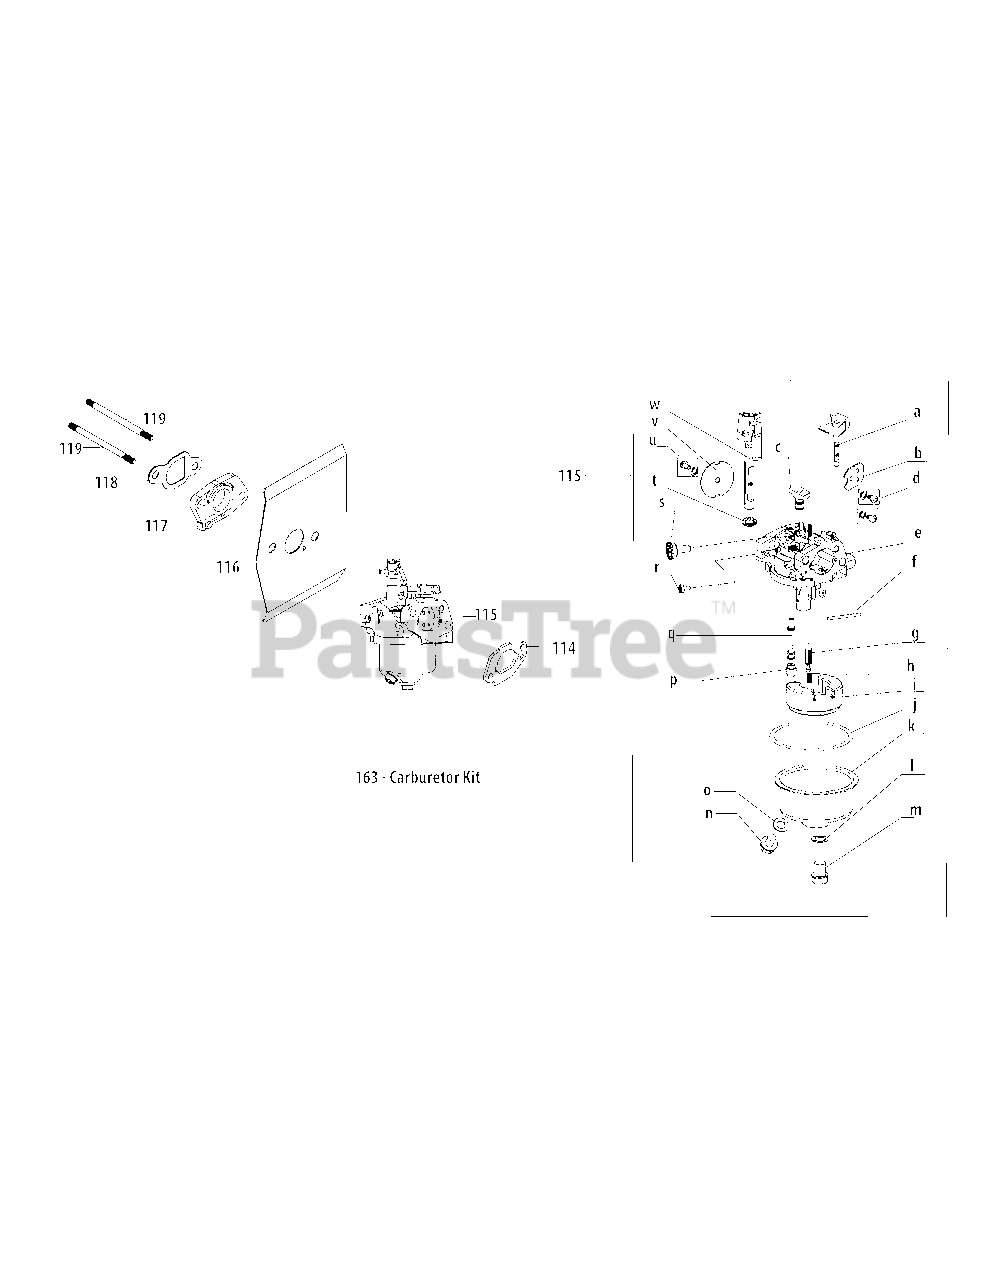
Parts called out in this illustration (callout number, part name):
114	Air Filter Base Gasket
115	Carburetor Assembly
116	Carburetor Gasket
117	Carburetor Insulator
118	Carburetor Insulator Gasket
119	Carb Stud M6×87
163	Carburetor Kit
